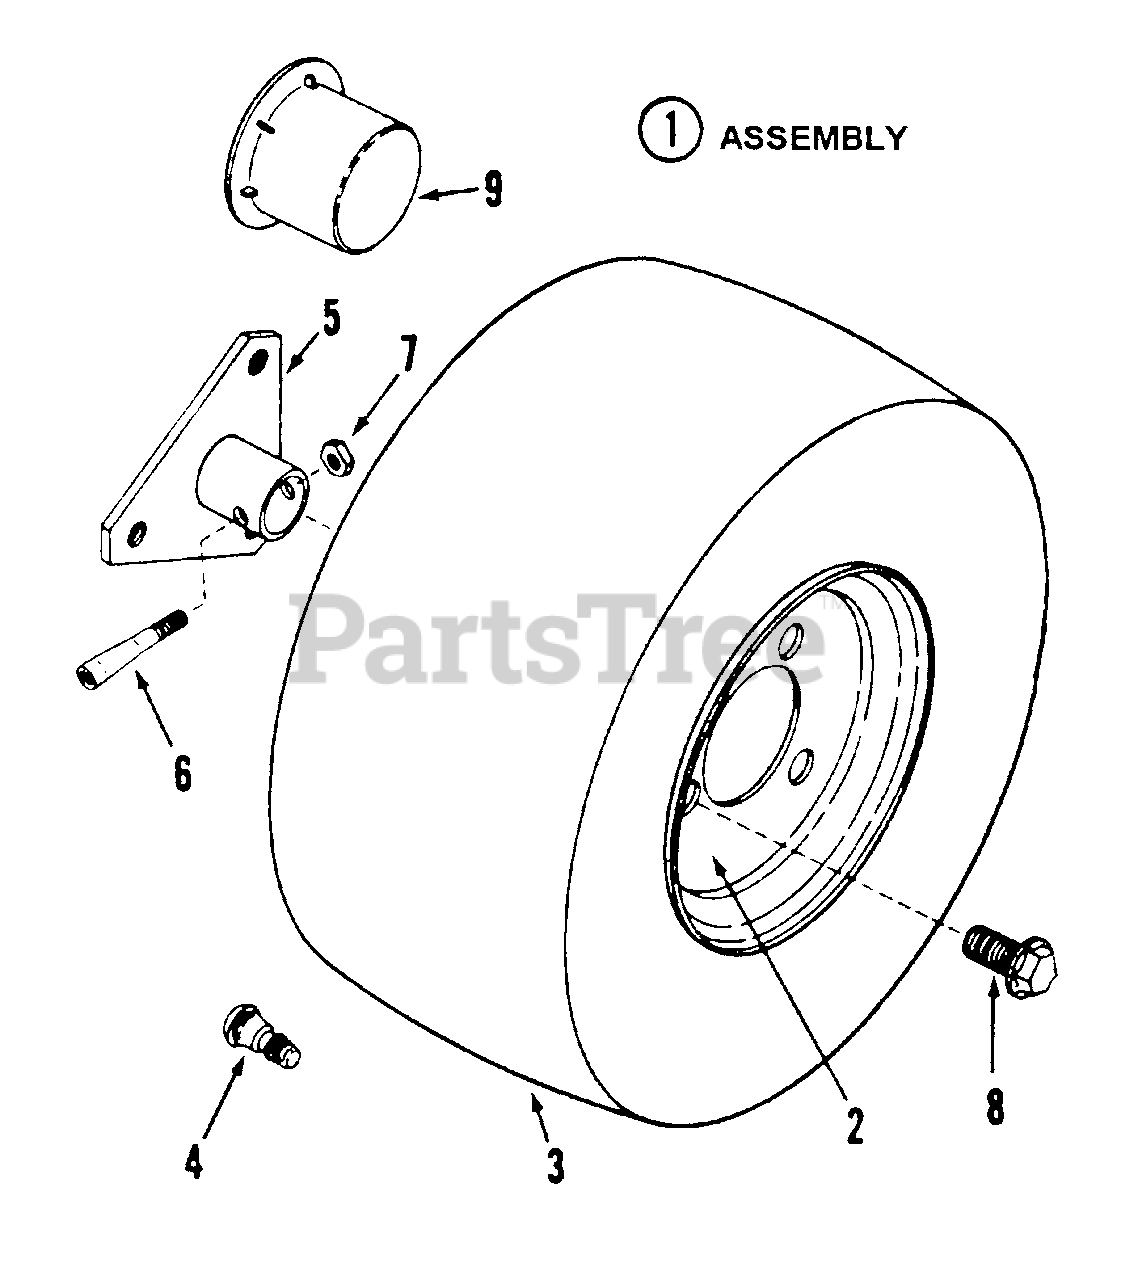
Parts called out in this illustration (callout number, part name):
1	* ASSEMBLY, Rear Tire & Rim 18x6.50-8
2	RIM, LT11 Rear Wheel
3	TIRE, 18 x 6.50 x 8
4	VALVE, Air
5	HUB, Rear Wheel
6	BOLT Tapered
7	NUT, 5/16-24 Lock
8	BOLT, Lug (1/2-20 x 3/4" HHCS)
9	HUB-CAP
